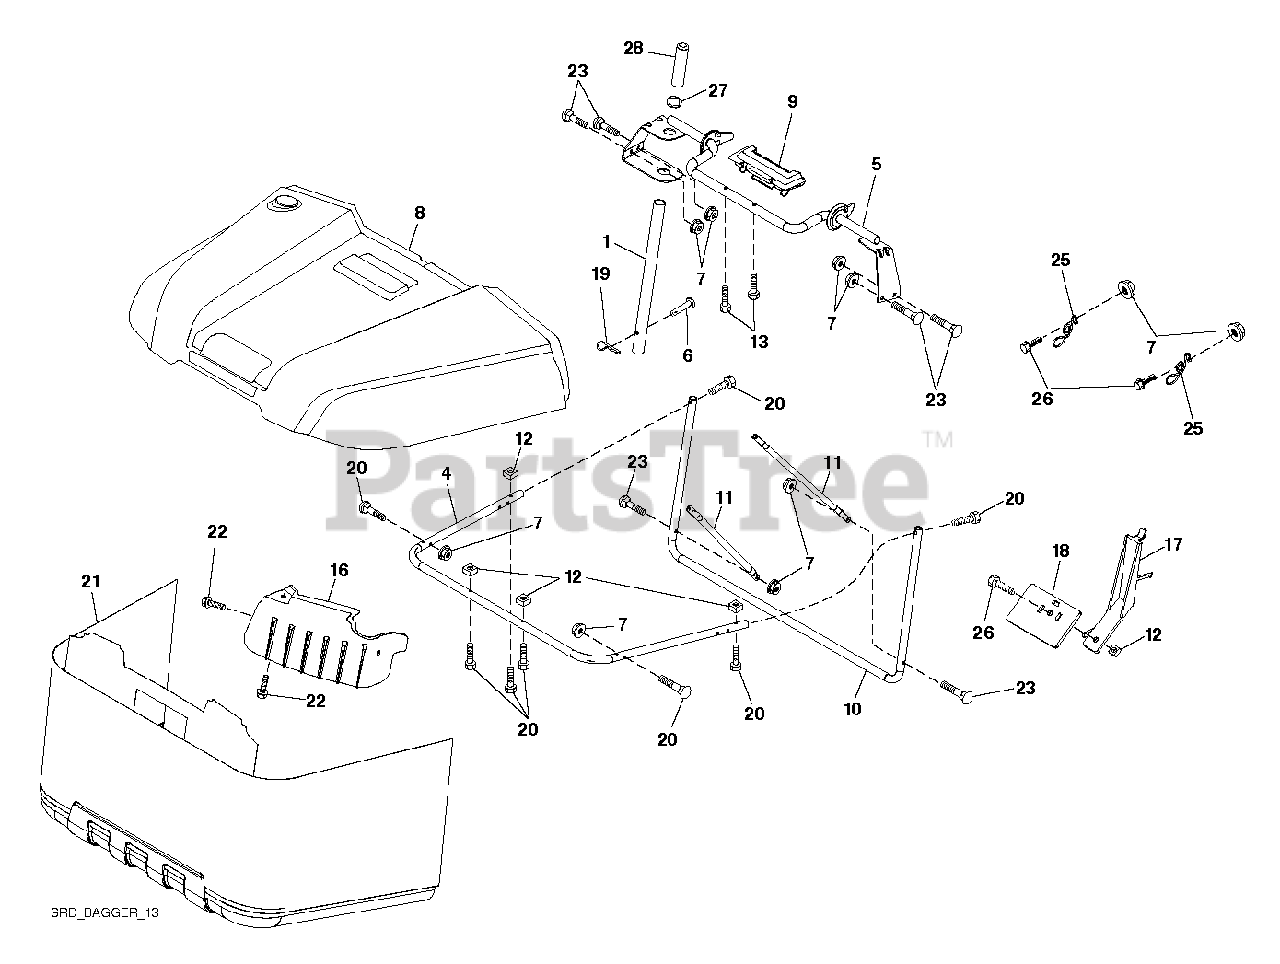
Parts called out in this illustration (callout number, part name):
1	TUBE.PNT.HDL.BAGGER.
6	RIVET,DRILLED
7	NUT T
19	PIN.COTTER.5/16.BOW TI
20	SCREW.HEXCAP.1/4-20X1.375(2 2)
22	SCREW.HI-LO.CONSOLE
26	SCREW HEX CRT
28	GRIP.HANDLE.BLACK
